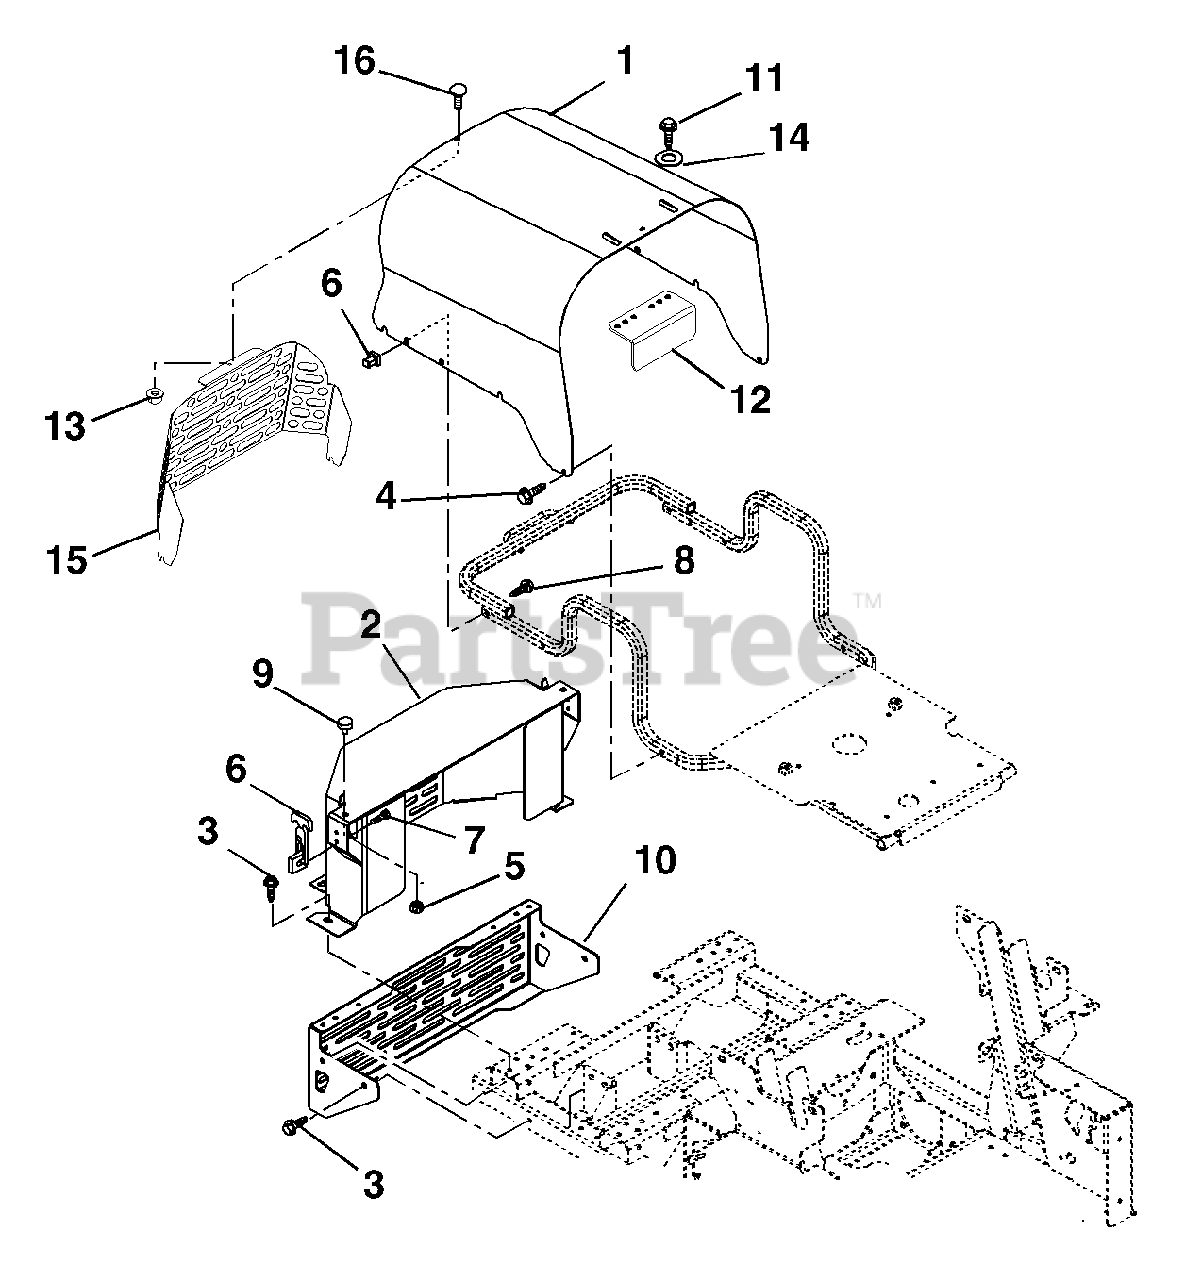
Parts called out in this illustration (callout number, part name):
2	Weldment, Belt Guard (060, 061, 318, 319)
2	Weldment, Belt Guard (058, 059)
3	Screw, Tapping .38-16 x .75 Hex Washer Head
4	Screw, Tapping .38-16 x .50 Hex Washer Head
5	Nut, Spin Lock, Flange .312-18
6	Latch, Rubber
7	Screw, Machine 10-24 x .50 Hex Washer Head
8	Screw, Machine 10-24 x 1.50 Hex Washer Head
9	Button, Bumper
10	Bumper, Rear
11	Screw, Tapping .25-20 x .50 Hex Washer Head
12	Guard, Radiator Cap (060, 061, 318, 319)
12	Guard, Radiator Cap (058, 059)
13	Nut, Locking Top Flange .25-20
14	Washer, Flat Steel .281 x .62 x .065
15	Guard, Hood
16	Bolt, Round Head Square Neck .25-20 x .50 Grade 5
